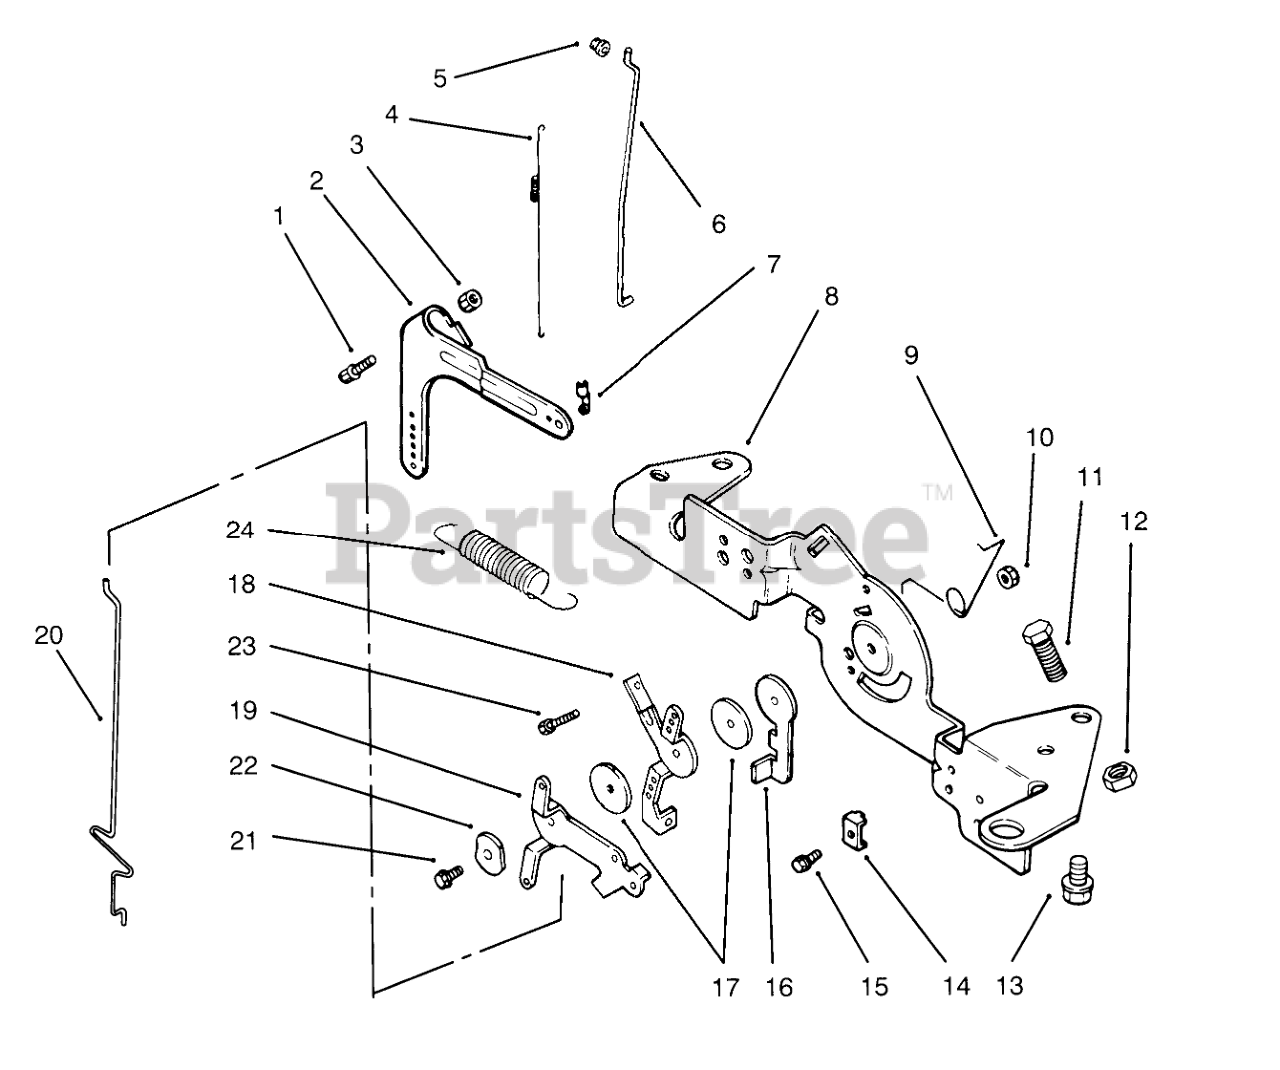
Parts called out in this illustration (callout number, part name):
1	Screw M6x1.0x25 (Only On: 72103)
2	Lever-Governor (Only On: 72103)
3	Nut M6x1.0 (Only On: 72103)
4	Spring-Linkage (Only On: 72103)
5	Bushing-Linkage (Only On: 72103)
6	Linkage-Throttle (Only On: 72103)
7	Bushing-Linkage (Only On: 72103)
8	Bracket-Control (Only On: 72103)
9	Spring-Choke Return (Only On: 72103)
10	Nut M5x0.8 (Only On: 72103)
11	Screw M5x0.8x16 (Only On: 72103)
12	Nut-Hex M4x0.7 (Only On: 72103)
13	Screw M6x1.0x16 (Only On: 72103)
14	Clamp-Cable (Only On: 72103)
15	Screw M5x0.8x16 (Only On: 72103)
16	Lever-Throttle Actuator (Only On: 72103)
17	Washer (Only On: 72103)
18	Lever-Throttle Control (Only On: 72103)
19	Lever-Choke (Only On: 72103)
20	Linkage-Choke (Only On: 72103)
21	Screw M5x0.8x20 (Only On: 72103)
22	Washer-Wave (Only On: 72103)
23	Screw M4x0.7x24 (Only On: 72103)
24	Spring-Governor (Only On: 72103)
